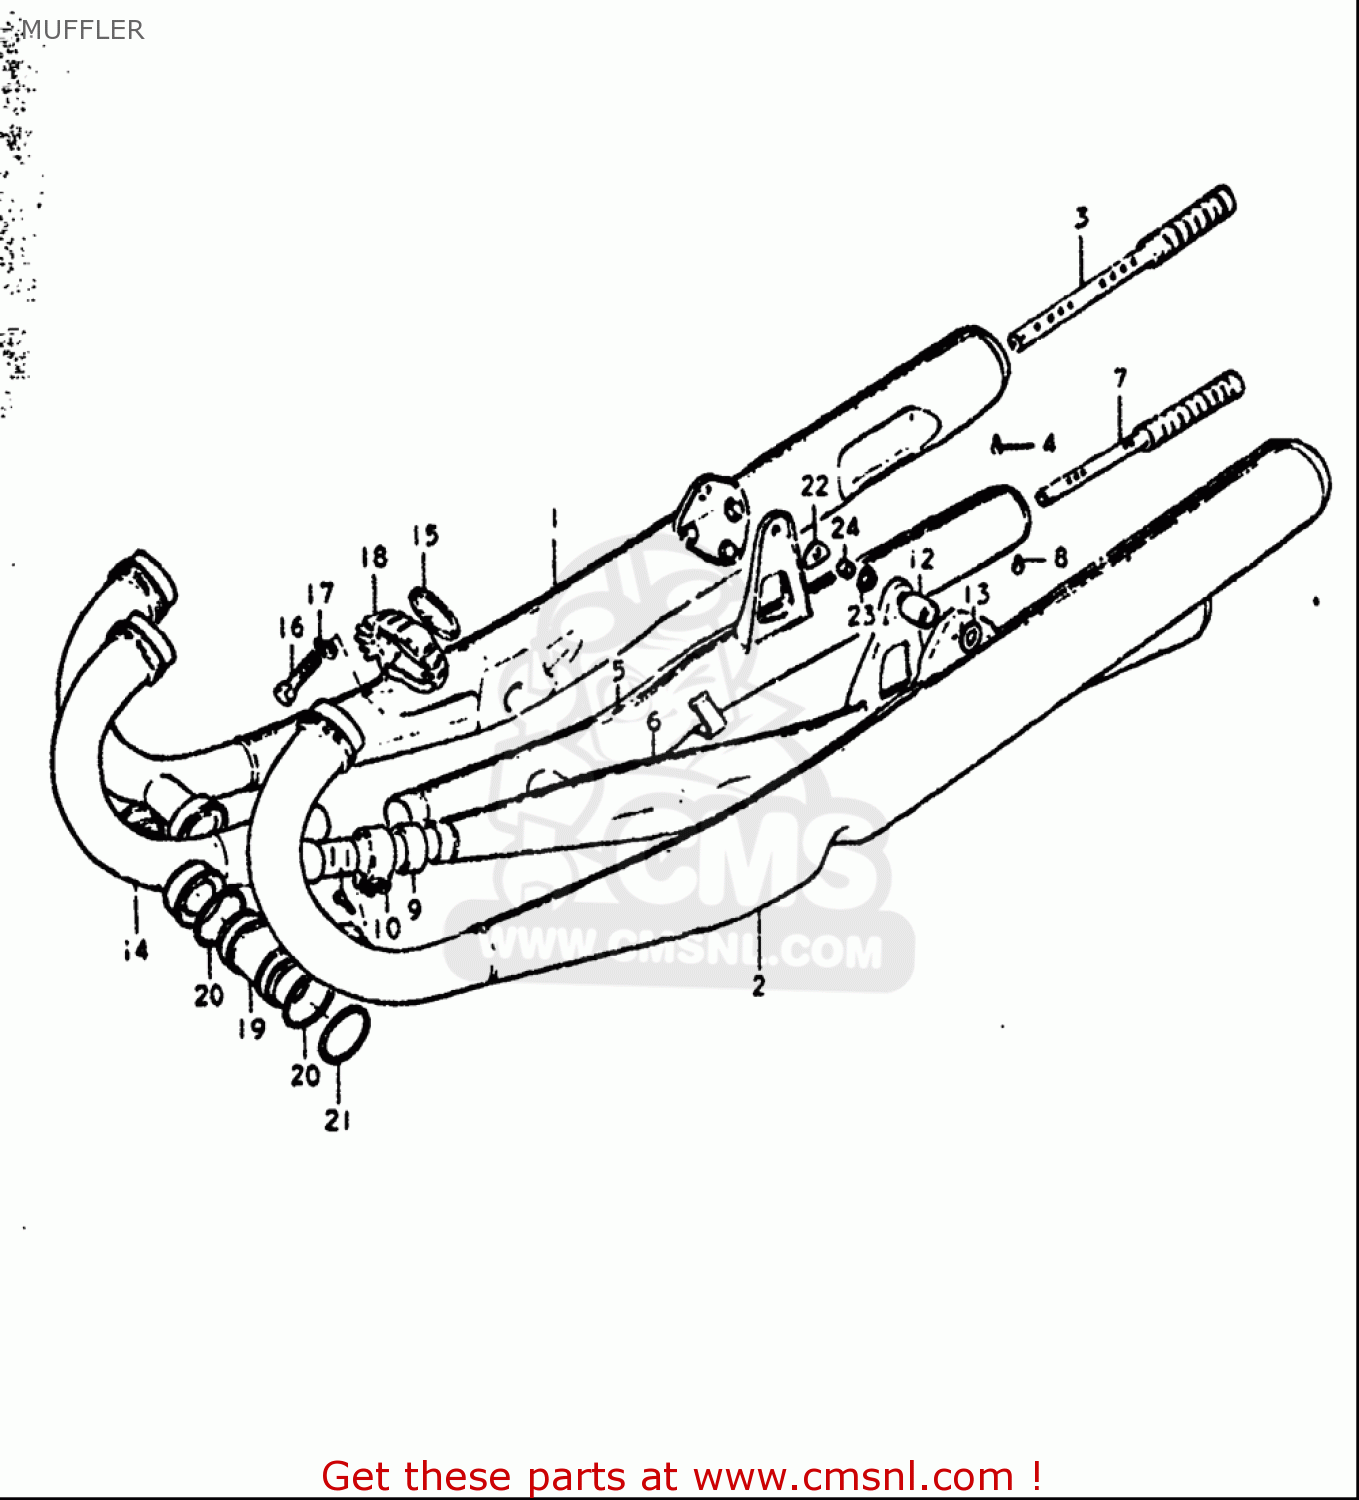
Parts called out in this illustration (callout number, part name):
3	PIPE,BAFFLE
4	SCREW(5X6)
7	PIPE,BAFFLE
8	SCREW(5X6)
9	CONNECTOR,MUFFLER
10	CLAMP
11	SCREW
12	BUSHING(10X23X35)
13	WASHER
15	GASKET,EXHAUST PIPE (NAS)
17	WASHER,LOCK
20	O RING(D:2.6,ID:39.7)
22	DAMPER,MUFFLER SUPPORT BRACKET
23	NUT (M10X1.25X9)
24	SPACER(10.1X15X4.8)
